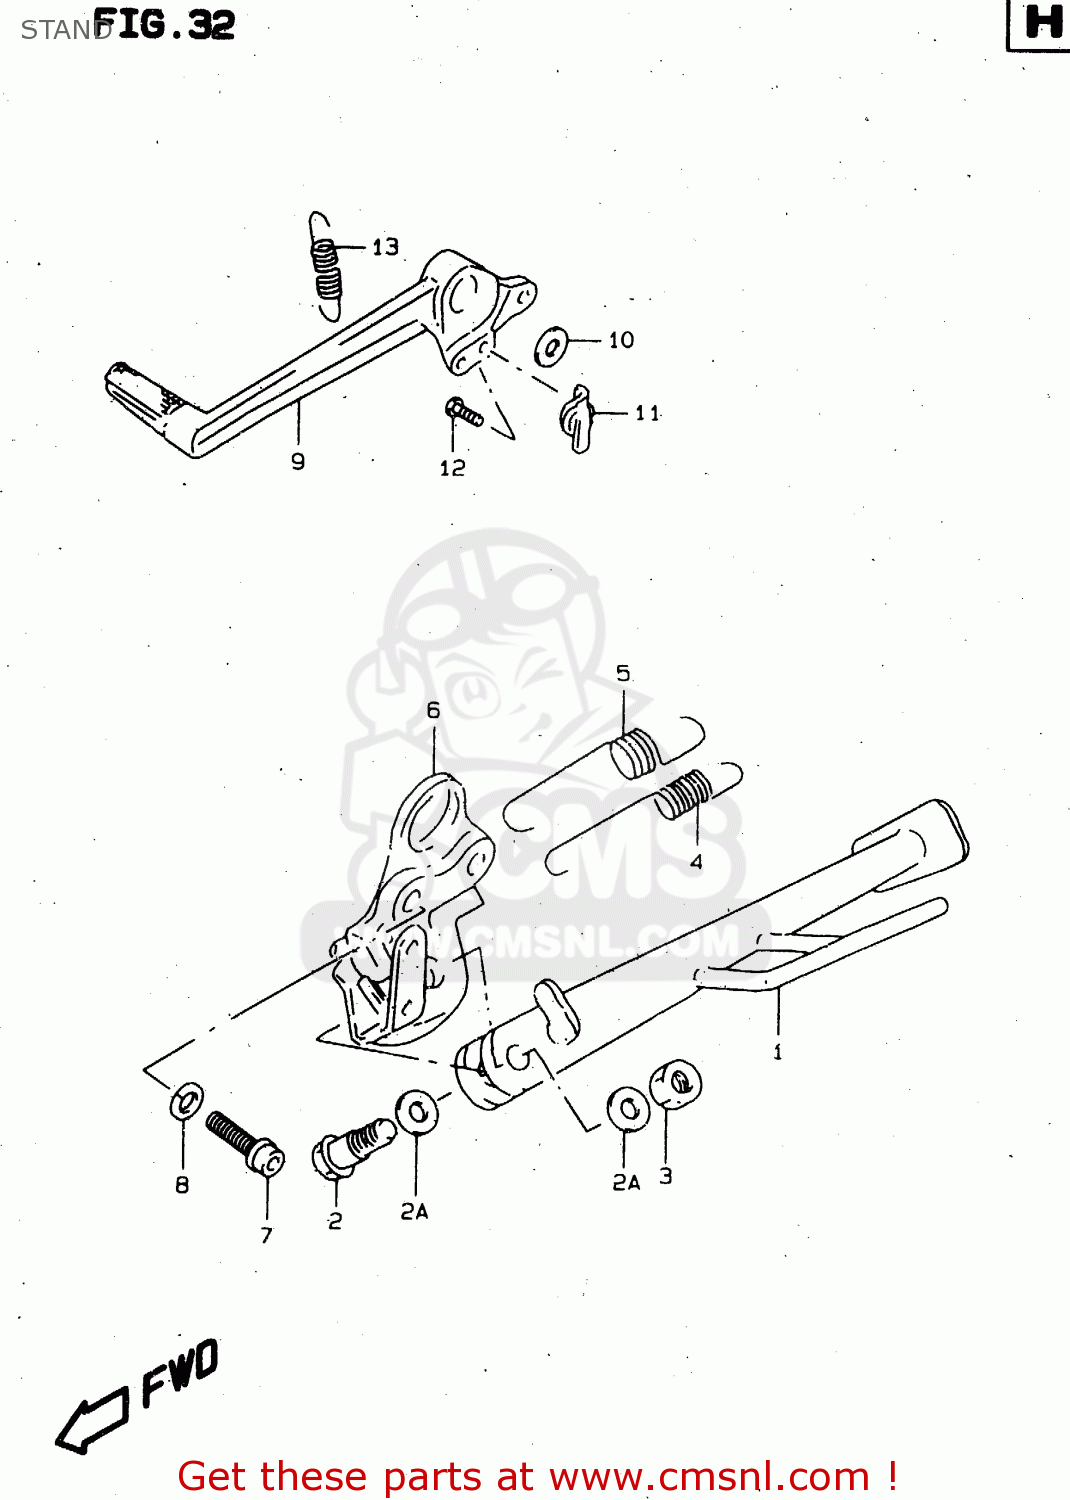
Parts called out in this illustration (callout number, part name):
1	STAND,PROP
2	BOLT(10X34)
2A	WASHER
3	NUT
4	SPRING
5	SPRING
6	BRACKET,PROP STAND
7	BOLT
8	LOCK WASHER
9	PEDAL,BRAKE
10	WASHER(18X24X1)
11	HOOK,RETURN SPRING
12	SCREW
13	SPRING
